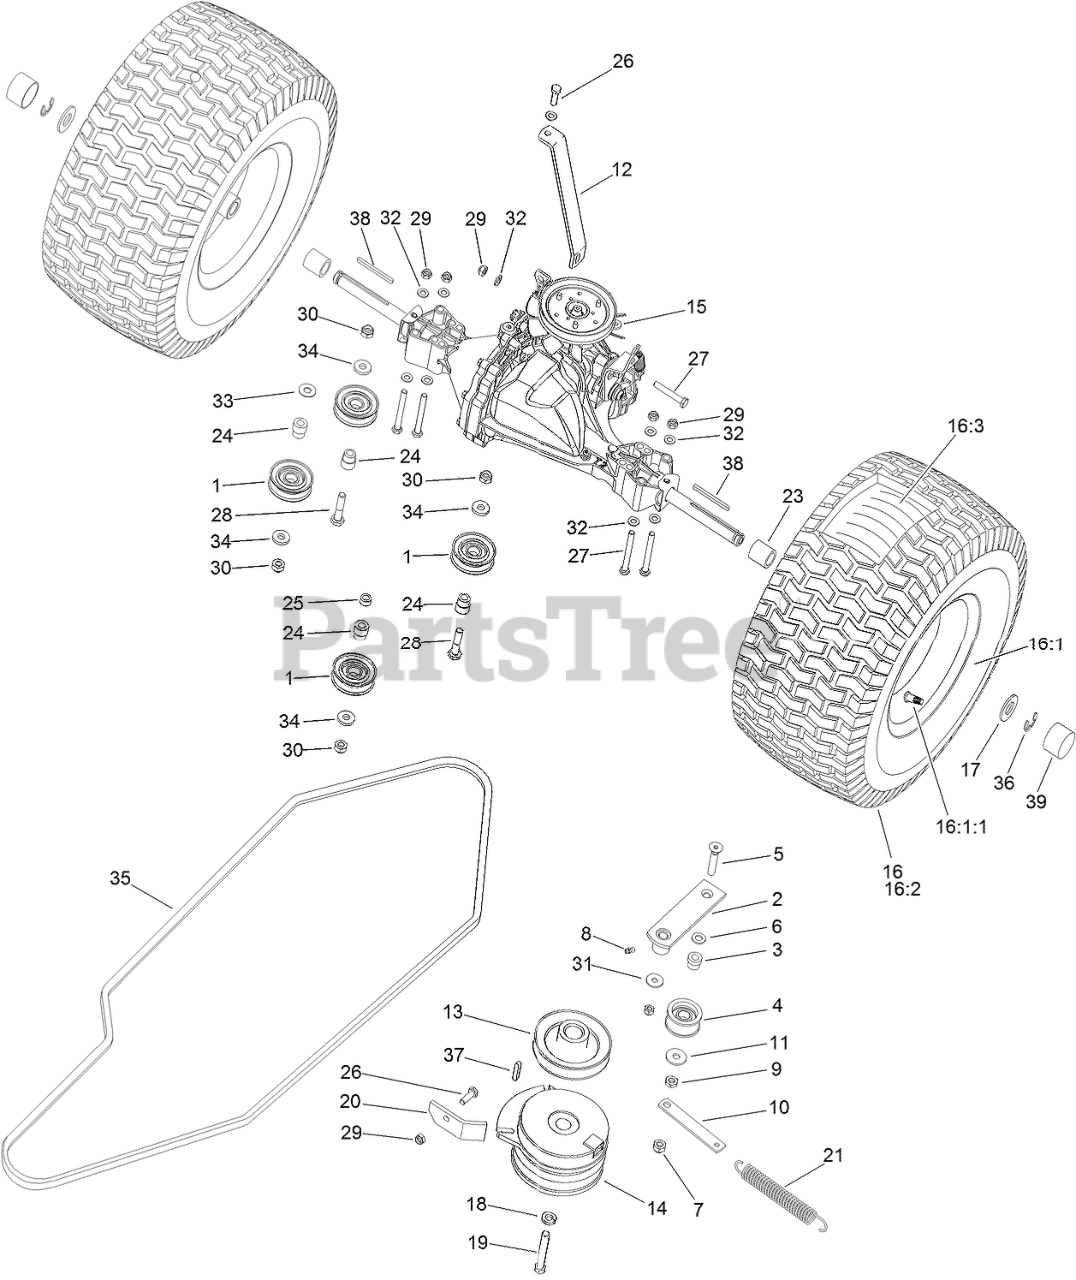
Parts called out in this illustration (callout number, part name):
1	PULLEY-IDLER
2	ARM-IDLER
3	BUSHING-IDLER
4	PULLEY-IDLER
6	WASHER-FLAT
7	NUT-LOCK, NI
8	FITTING-GREASE
9	NUT-HEX
10	BRACKET-TENTION
11	WASHER
12	BRACKET
13	PULLEY-ENGINE
14	CLUTCH-ELECTRIC
15	TRANSMISSION ASM
16	WHEEL ASM
16:1	RIM-REAR
16:1:1	Valve-Tire
16:3	Tube
17	WASHER
18	WASHER-SPRING, BELLEVILLE
19	SCREW-HH
20	BRACKET-RETAINER
21	SPRING
23	SPACER-AXLE
24	BUSHING
25	SPACER
26	SCREW-HH
27	CAPSCREW
28	SCREW-HH
29	NUT-LOCK, NI
30	NUT-LOCK, NI
31	WASHER-PLAIN
32	WASHER-PLAIN
33	Washer
34	WASHER-FLAT
35	V-BELT, TRACTION
36	CLIP-SPRING
37	KEY-SQUARE
38	KEY-SQUARE
39	CAP-HUB
